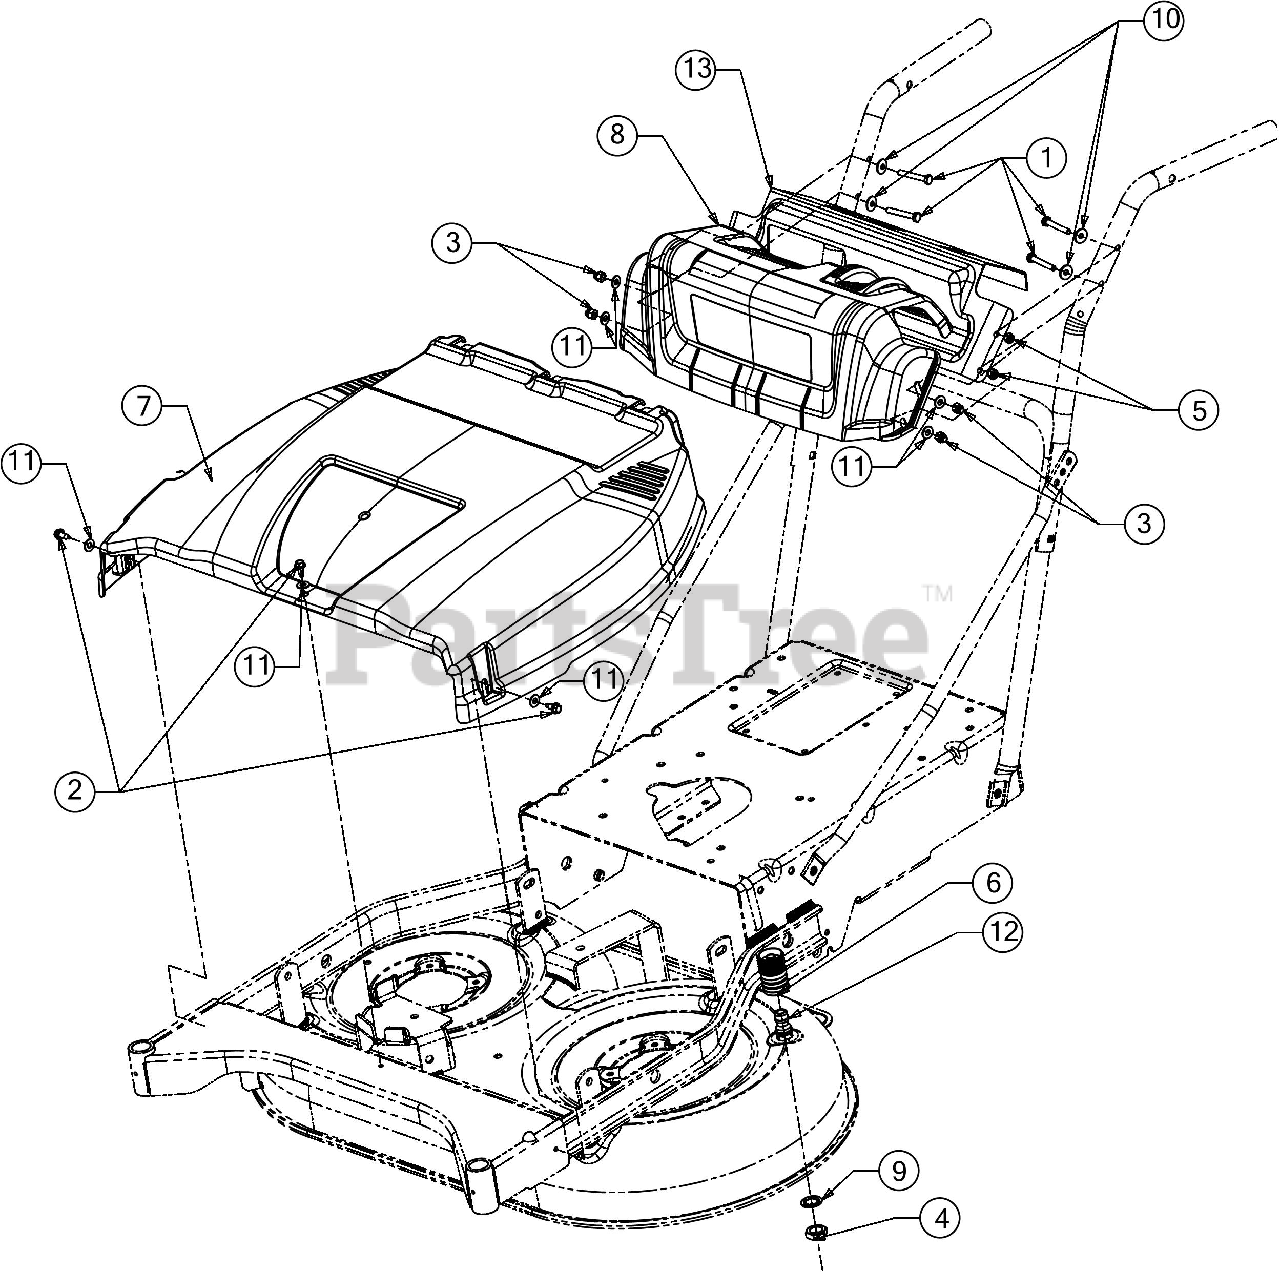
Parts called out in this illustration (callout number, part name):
1	HEX SCREW 1/4-20 X 1.75
2	SCREW 1/4-14 X .625
3	HEX ACORN NUT
4	HEX NUT
6	WATER NOZZLE
7	WIDECUT BELT COVER
8	HANDLE PANEL COVER
9	LOCK WASHER 5/8
10	SPRING WASHER BELL
11	FLAT WASHER
12	DECK WASH NOZZLE
13	HANDLE PANEL W/KEY
